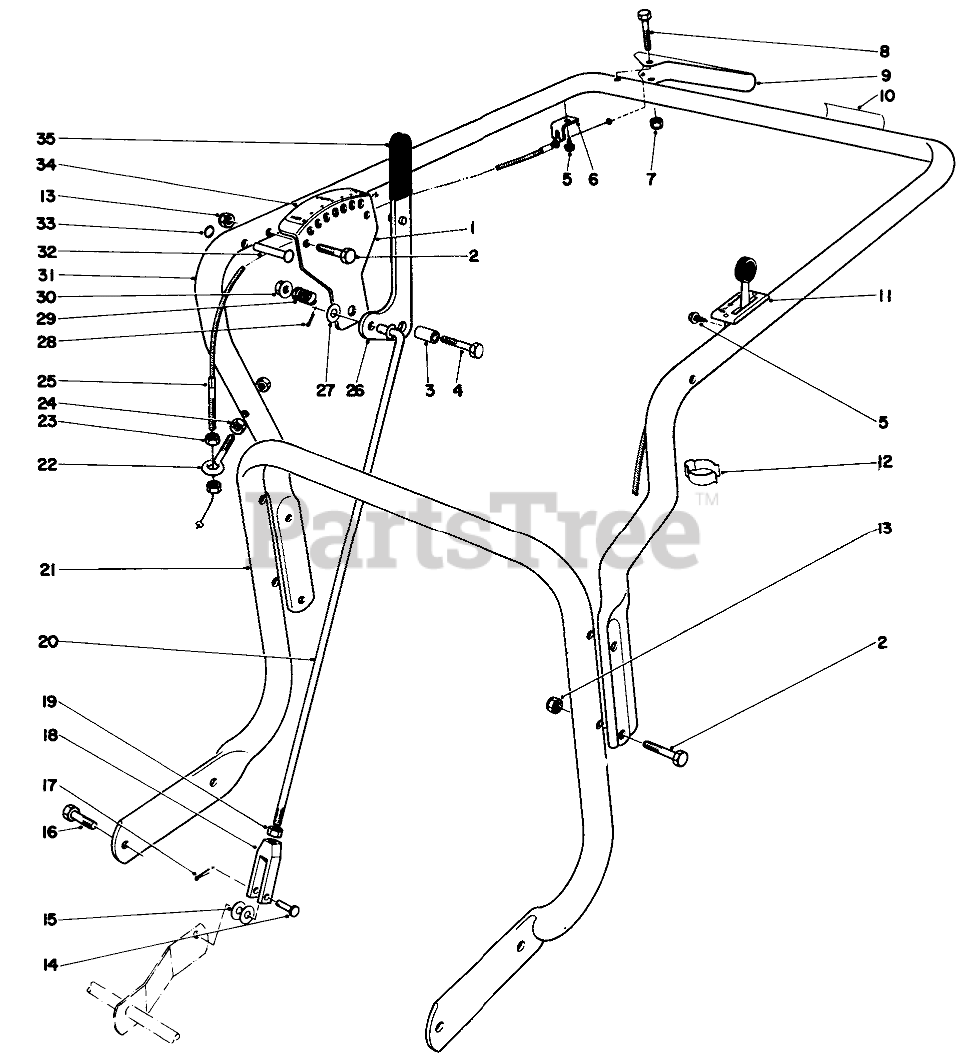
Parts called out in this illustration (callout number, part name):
1	Adjustment Bracket
2	SCREW-HH
3	SPACER
4	SCREW-HH
5	SCREW-HWHTF
6	RETAINING-CLIP
7	NUT-LOCK, NI
8	SCREW-HH
9	Lever, Traction Control
10	TRACTION CONT DECAL
11	Throttle Control
12	BODEN CLIP
13	NUT-LOCK, NI
14	PIN-CLEVIS
15	WASHER-PLAIN
16	SCREW-HH
17	PIN-COTTER
18	Yoke
19	NUT-HJ
20	Connector Rod
21	HANDLE
22	Eye Bolt
23	NUT-KEPS
24	NUT-LOCK, CONE
25	BODINE CABLE
26	Adjustment Handle
27	WASHER-FLAT
28	PIN-COTTER
29	SPRING-COMPRESSION
30	NUT-HF
31	Handle
32	RIVET
33	RING-GRIP
34	HT ADJ DECAL
35	GRIP-HANDLE
